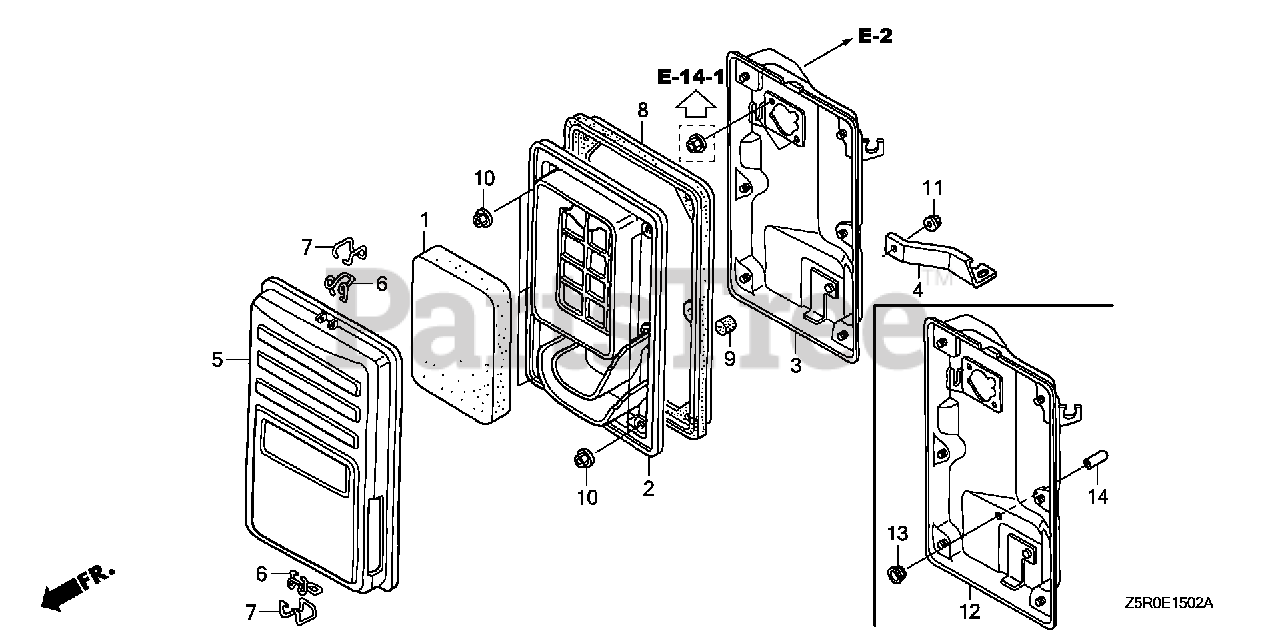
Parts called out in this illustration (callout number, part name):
1	ELEMENT, AIR CLEANER
2	SEPARATOR, AIR CLEANER
4	STAY, AIR CLEANER
5	COVER, AIR CLEANER
6	CLIP A, AIR CLEANER WIRE
7	CLIP B, AIR CLEANER WIRE
8	SEAL, AIR CLEANER
9	FILTER, DRAIN TUBE
10	NUT, FLANGE (5MM)
11	NUT, FLANGE (6MM)
12	HOUSING, AIR CLEANER
13	GROMMET, AIR CLEANER
14	CAP, SEALING
